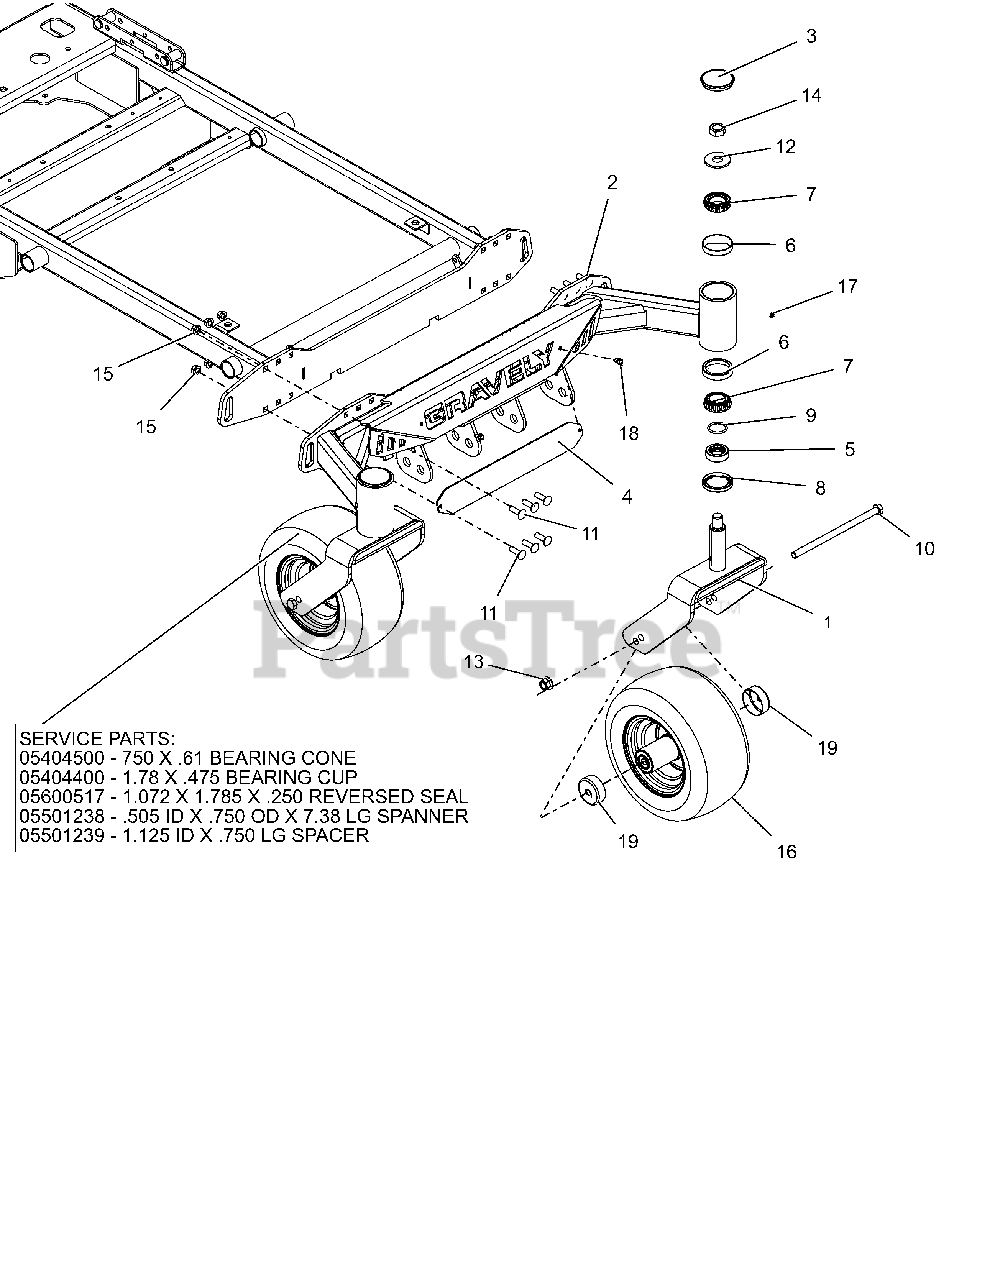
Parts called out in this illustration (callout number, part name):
1	CASTER FORK WMT - RED
2	WLDMT, FRONT 60 AXLE
3	CAP, DUST
4	BACKER, NAMEPLATE
5	SPACER, FRONT CASTER FORK
6	BRG-CUP 2.328X.465
7	BRG-CONE 1.25X.66
8	SEAL, OIL 1.75 X 2.332 X .312
10	@BLT-HEX .50-13X9.00 GR5 YWZC
11	@BLT-RDHDSQNK .38-16X1.25 G5YZ
12	@WSHR-FL-STL.812X2.00X.148YWZC
13	@NUT-LK-NYL-FLG .50-13 YWZC
14	NUT-JAM TOPLK .75-16 YWZC
15	@NUT-LK-TOP-FLG .38-16 YWZC
16	ASM, WHL/TIRE 13X6.50-6 SEMI
16	BRG-CONE .750X.61
16	BRG-CUP 1.781X.475
16	SEAL, 1.125 X 1.781 X .469
16	SPANNER,.505ID X.750OD X7.38LG
16	SPACER, 1.125 ID X .750 LG
17	FTG, .25-28 FLUSH MNT GREASE
18	SCR-TAP .25-20X.50 HWH TR YWZ
19	SHIELD, WHEEL BEARING
